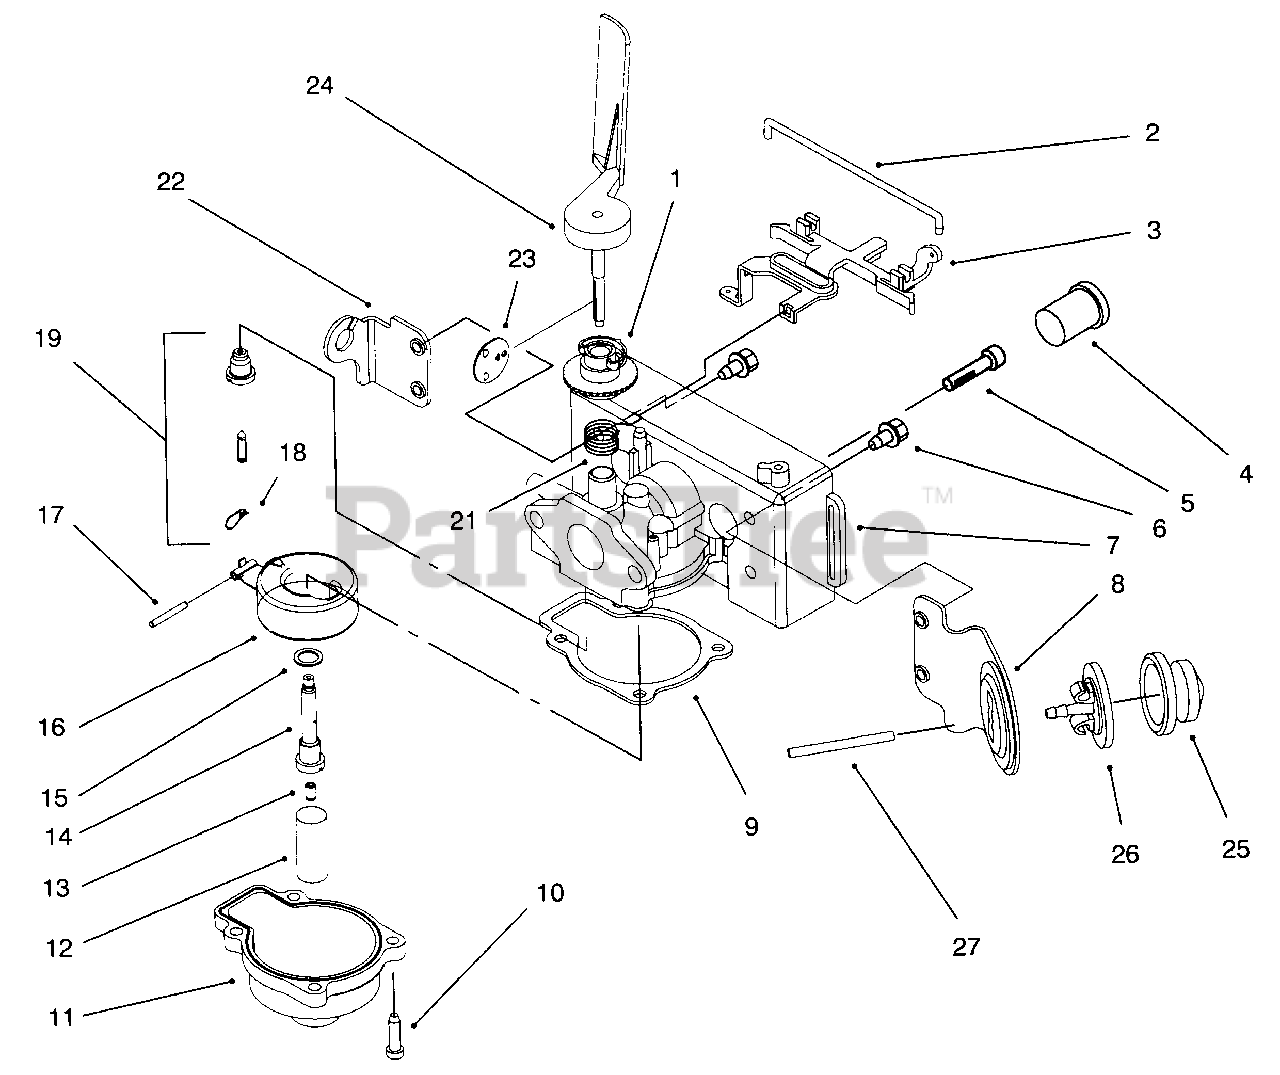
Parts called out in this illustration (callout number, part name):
1	Collar-Adjustment
2	Retainer
3	Lever-Speed Adjust
4	Plug
5	Screw-Pan Hd. Sems
7	Body-Carburetor
8	Bracket-Primer
9	Gasket-Float Chamber
11	Float Chamber
12	Filter-Fuel
13	Main Jet
16	Float & Arm Assembly
18	Clip
19	Float, Valve, & Body Ass'y
21	Spring-Governor
22	Bracket-Throttle Control
23	Disc-Throttle
24	Air Vane & Shaft
25	Bulb-Primer
26	Body-Primer
27	Hose-Primer
